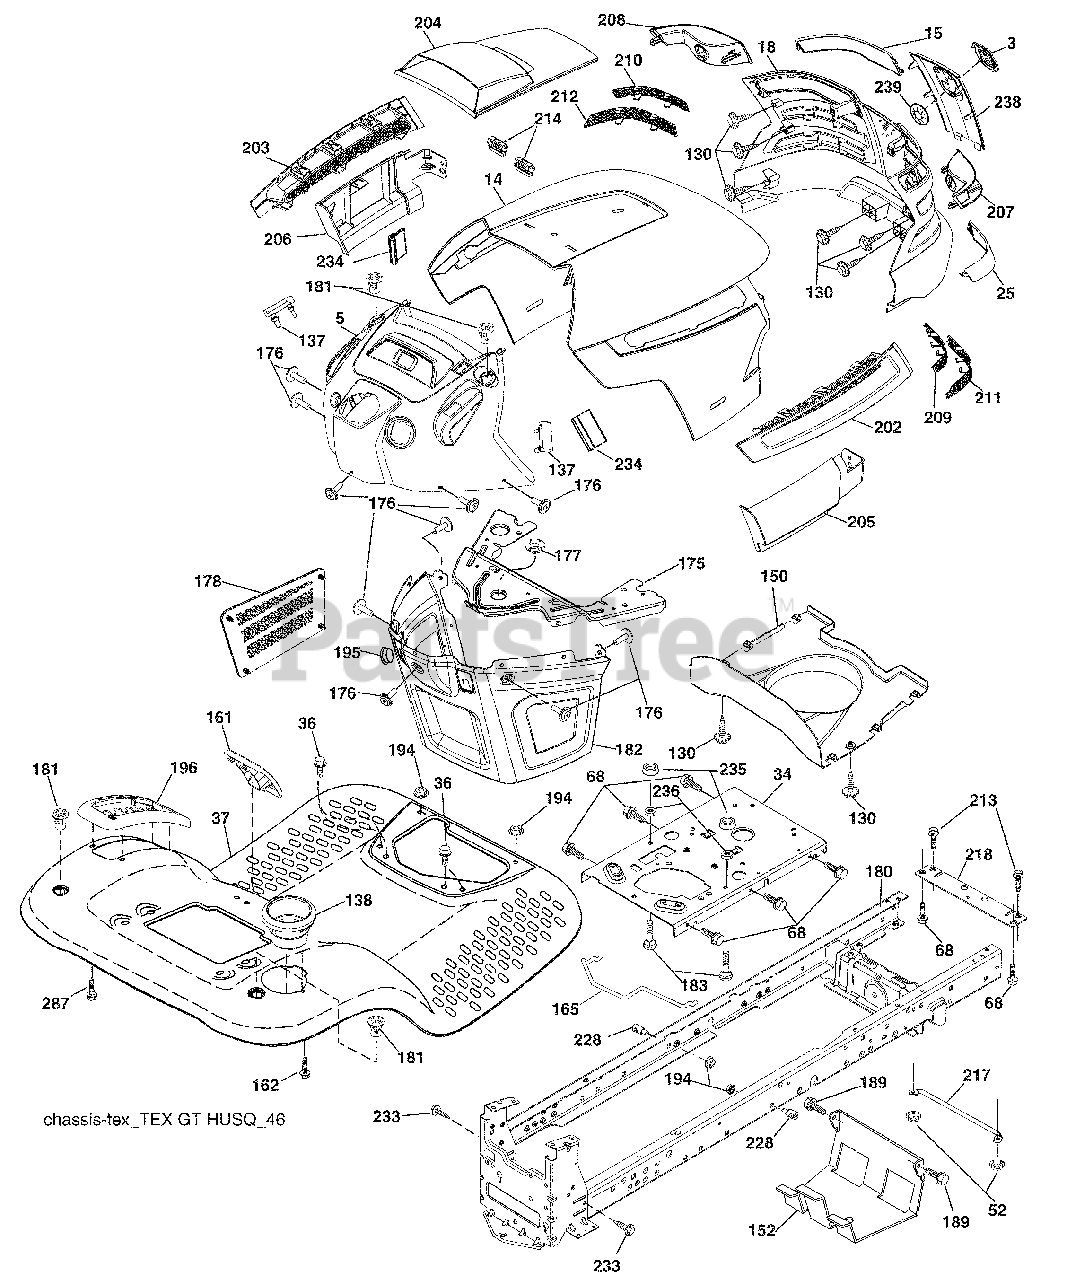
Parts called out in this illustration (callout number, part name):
3	Logo
14	Hood
18	Grille Asm.
34	Plate Engine
36	Screw 5/16-18 x 3/4
52	Nut Lock 5/16-18
68	Screw 5/16-18 x 1/2
130	Screw #10 x 0.750 BOS Thread
137	Bumper Dash
138	Cupholder
152	Shield Browning
161	Window Fuel
165	Support Tank Rear
175	Crossmember
176	Screw 10-24 x 5/8
177	Bushing Steering
178	Cargo Net Asm.
180	Chassis
181	Bushing Mtg. Fender Crgo
182	Dash Lower
183	Bolt Fin Hex 5/16-18 unc x 1-1/4
189	Screw 5/16-18 x 3/4
194	Nut Lock Hex Flange 5/16-18
195	Plug Hole Dash Lower
196	Console Asm. Deck Lift
202	Vent Side Hood RH
203	Vent Side Hood LH
204	Vent Top Hood
205	Skirt Hood Side RH
206	Skirt Hood Side LH
209	Insert Hex Top RH
210	Insert Hex Top LH
211	Insert Hex Bottom RH
212	Insert Hex Bottom LH
213	Bolt 5/16-18 unc x 3/4
214	Clip Retainer Tinner
218	X-Piece Hood Stop
228	Stud Fastner
233	Bolt, Shoulder
234	Bumper Hood
235	Spacer Fender
236	Nut Lock 5/16-18 unc
287	Screw Hex Washead 1/4-20 x 3/8
